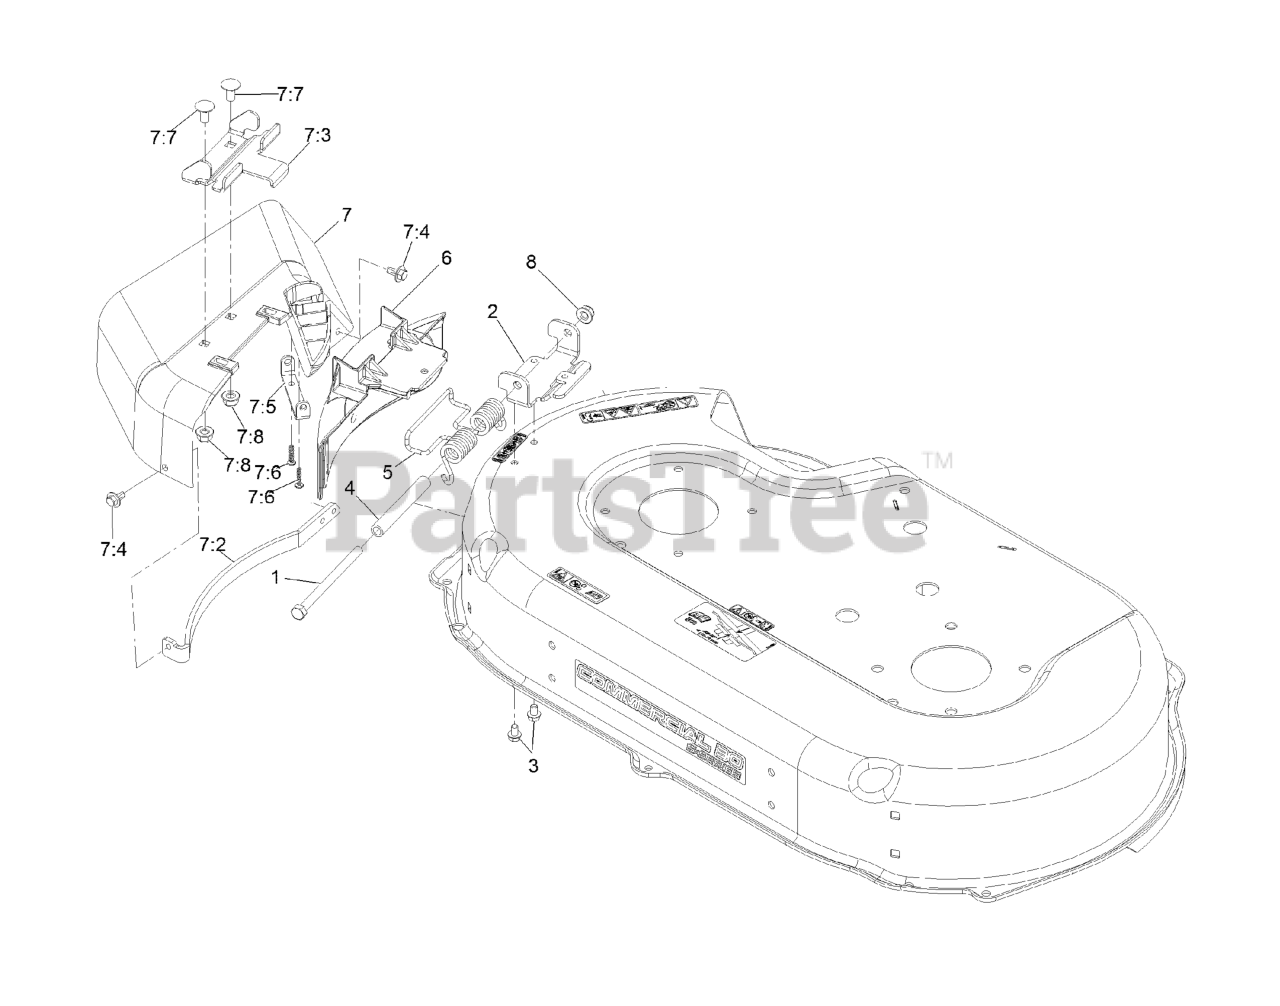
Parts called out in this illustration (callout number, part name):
1	SCREW-HH
5	SPRING-TORSION
6	COVER-DISCHARGE
7	SIDE DISCHARGE CHUTE ASM
7:2	GUARD-CHUTE
7:3	BRACKET-CHUTE
7:4	SCREW-HHFTF
7:5	BRACKET-COVER
7:6	SCREW-PPH
7:7	SCREW-CARR
7:8	NUT-HF, NI
8	NUT-HF, NI
